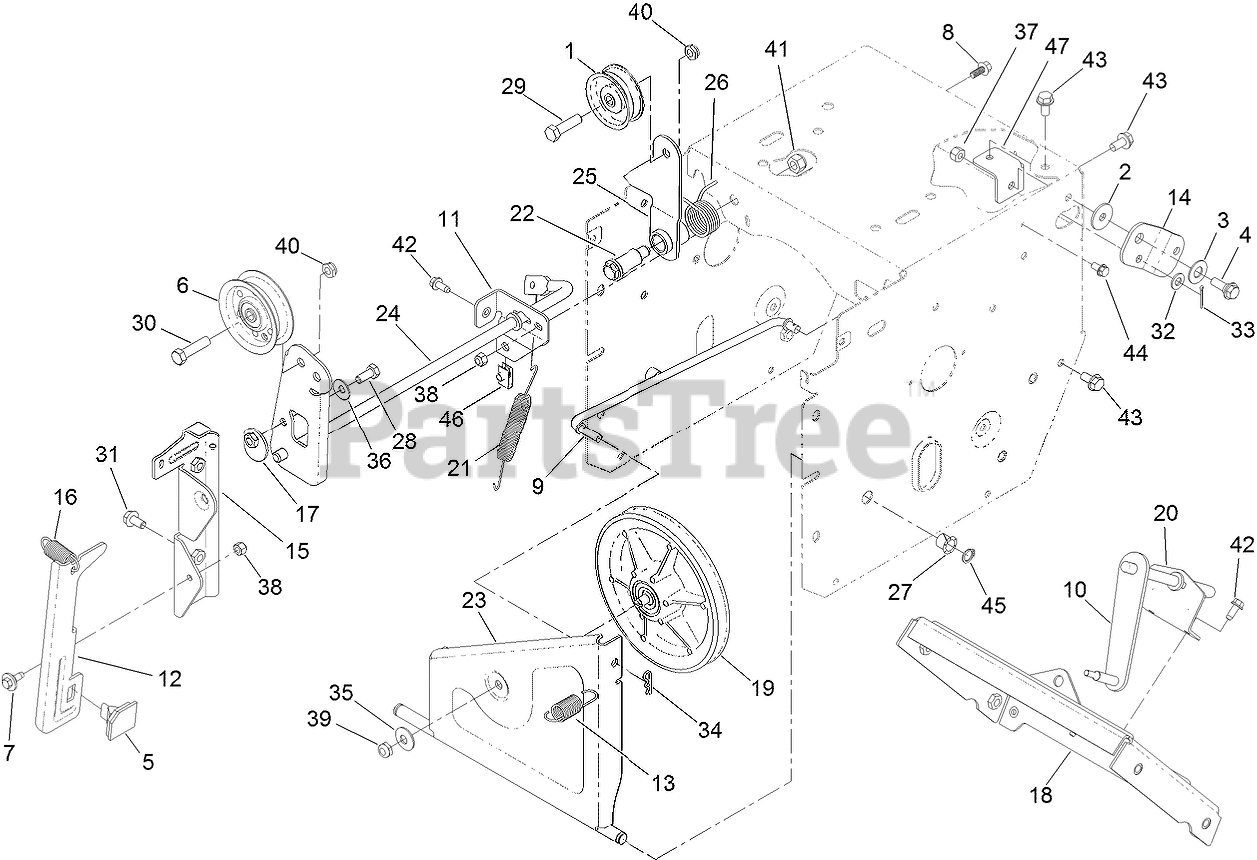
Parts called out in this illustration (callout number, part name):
1	PULLEY-IDLER
2	WASHER-PIVOT
3	WASHER
4	SCREW-SHOULDER
5	PAD-BRAKE
6	PULLEY-IDLER
7	SCREW-SHOULDER
8	SCREW-HHF
9	LINK-SPEED, CONTROL
10	TRACTION LEVER ASM
11	BRACKET-IMPELLER, CLUTCH
12	ARM-BRAKE
13	SPRING-EXTENSION
14	BELLCRANK
15	BRACKET-IMPELLER, IDLER
16	SPRING-EXTENSION
17	NUT ASSEMBLY
18	SHIFT PLATE ASM
19	PULLEY-TRACTION
20	BRACKET-SHIFT, ROD
21	SPRING-EXTENSION
22	BOLT-SHOULDER
23	BRACKET-WHEEL, FRICTION
24	IMPELLER CLUTCH ASM
25	ARM-IDLER, TRACTION
26	SPRING-TORSION
27	BUSHING-NYLINER
28	SCREW-HH
29	SCREW-HH
30	SCREW-HH
31	SCREW-HHF
32	WASHER-PLAIN
33	PIN-COTTER
34	PIN-HAIR
35	WASHER-BELLEVILLE
36	WASHER-BELLEVILLE
37	NUT-HEX
38	NUT-HEX
39	NUT-HEX
40	NUT-HEX
41	NUT-HEX
42	SCREW-HWH
43	SCREW-HWHTF
44	SCREW-HWH
45	RING-RETAINING
47	BRACKET-FRAME, LH
